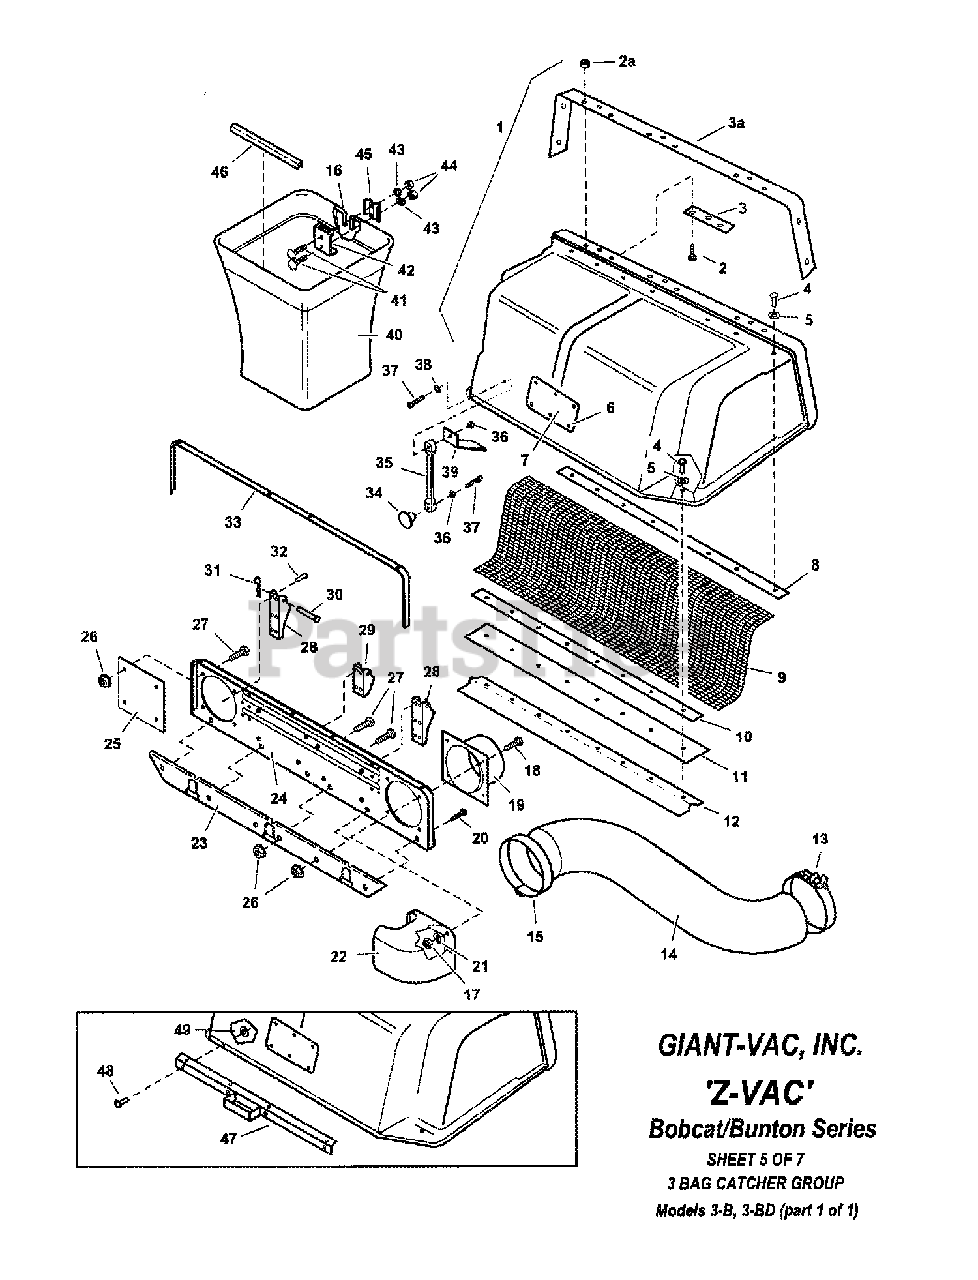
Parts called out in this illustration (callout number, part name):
1	ASSEMBLY, Cover & Screen
2	SCREW, 1/4-20 x 3/4" Hex Head Cap, GR5
2	SCREW, 1/4-20 x 5/8" Hex Head Cap, GR5
3	WELDMENT, Hinge
4	POP RIVET, 3/16 x .565 Aluminum
5	WASHER, Rivet .188 (.20 I.D. x .500 O.D.)
6	CLIP, Canoe
7	* DECAL, Safety, Grass Bag
8	CLAMP
9	SCREEN, Catcher
10	CLAMP, Seal
11	SEAL, Catcher Top
12	ANGLE, Screen
13	HOSE CLAMP, Lower, Fast Vac
14	HOSE, Snapper Fast Vac
15	HOSE CLAMP, Upper
16	HOOP, Grass Bag
17	NUT, 5/16-18 Hex Nyloc
18	SCREW, 5/16-18 x 1" Hex Head Cap, GR5
19	WELDMENT, Hose Adapter
20	SCREW, 1/4-20 x 1/2" Hex Washer Self-Tap
21	WASHER, 5/16" Flat
22	DEFLECTOR, Grass Bag
23	ASSEMBLY, Channel
24	WELDMENT, Backplate
25	COVER, Backplate
26	NUT, 5/16-18 Hex Flange Lock
27	SCREW, 5/16-18 x 3/4" Hex Head Cap, GR5
28	HINGE
29	HINGE
30	PIN, 3/8 x 2-3/4"
31	HAIR PIN, .093 Dia.
33	SEAL, Catcher Top
35	STRAP, Rubber
36	NUT, #10-32 Hex Nyloc
37	SCREW, #10-32 x 1-1/2 Hex Washer Head Machine w/Nylon Patch
38	WASHER, .19 x .38 x .06 Flat
39	COVER, Support
40	GRASS BAG
41	BOLT, 5/16-18 x 3/4" Square Neck Carriage, GR5
42	HANGER, Grass Bag
43	WASHER, 5/16" Split Lock
44	NUT, 5/16-18 Hex, GR5 or B
45	CLAMP, Grass Bag
46	TUBE CLIP, Grass Bag
47	WELDMENT, Cover Handle
48	SCREW, 8-32 x 1/2" Cross Recess Pan Head
49	WASHER, #8 External Tooth Lock
